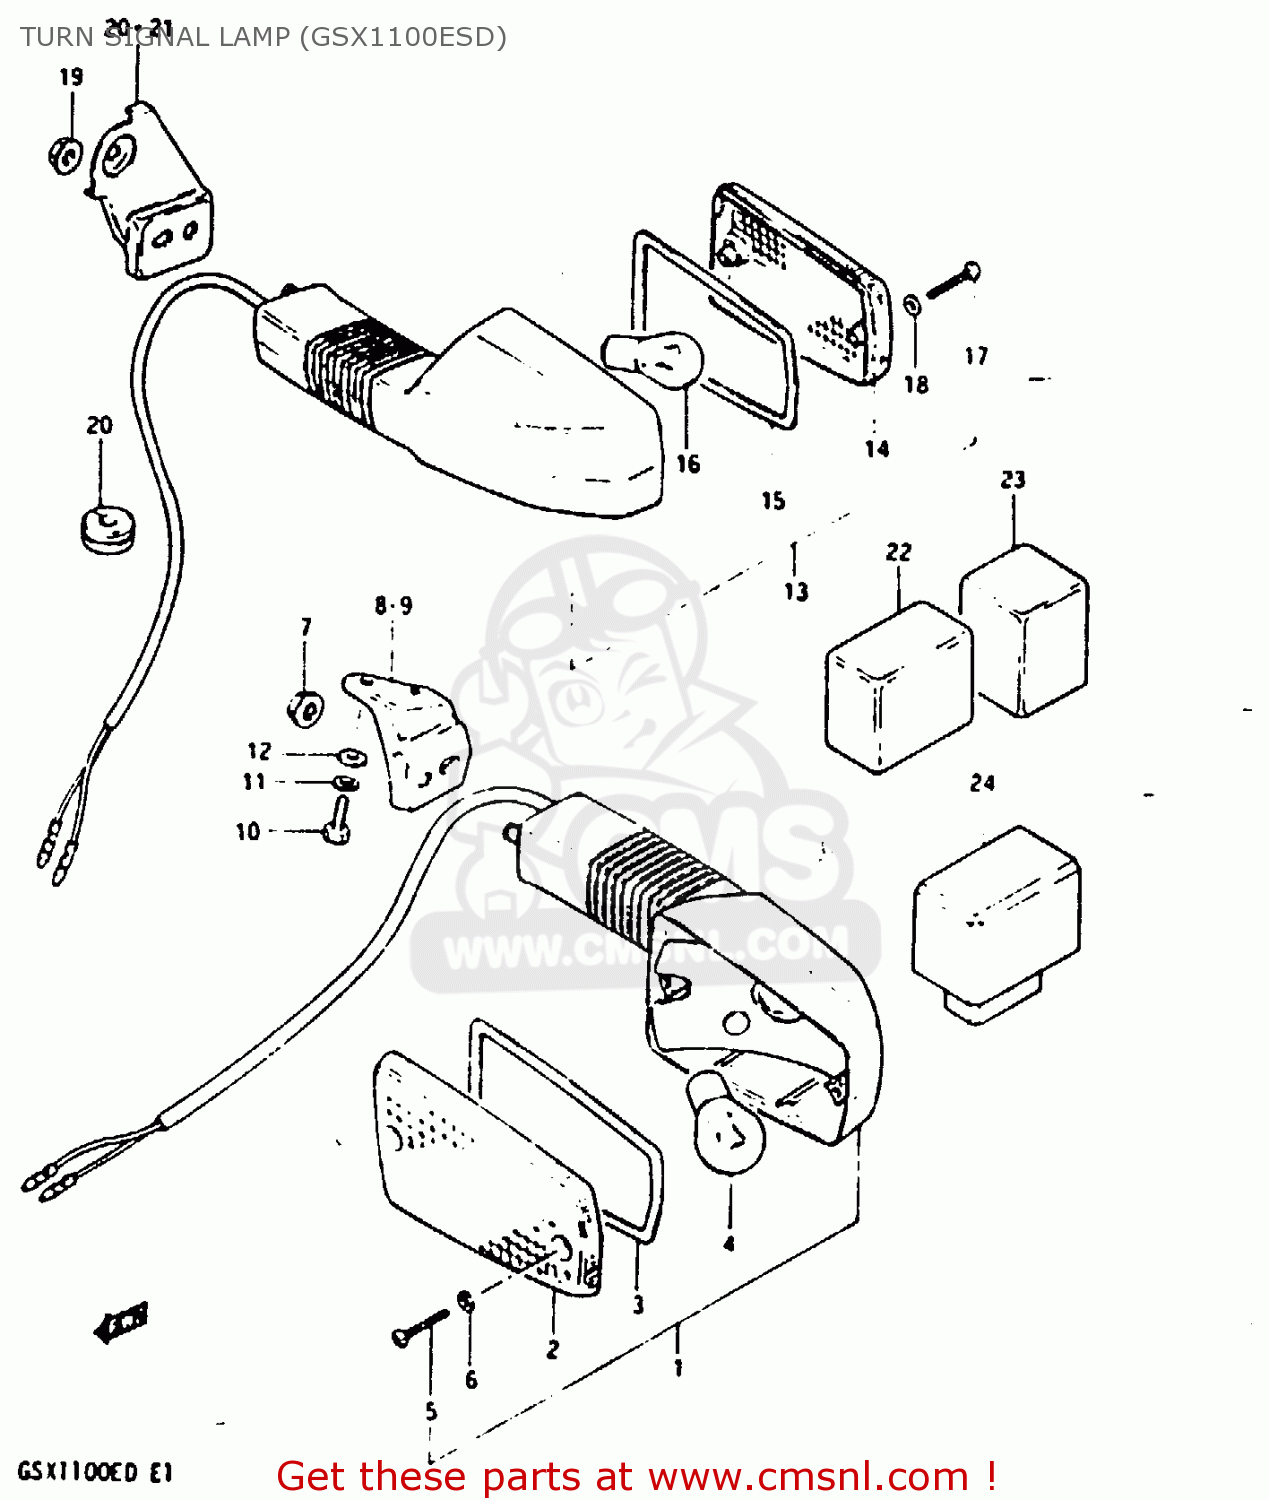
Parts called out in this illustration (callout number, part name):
1	LAMP ASSY, FRONT TURN SIGNAL
2	LENS
3	GASKET (NAS)
4	BULB(12V21W)
5	SCREW
6	GASKET (NAS)
7	NUT
8	BRACKET,FRONT TURN SIGNAL
9	BRACKET,FRONT TURN SIGNAL
10	BOLT
11	LOCK WASHER
12	WASHER
13	LAMP ASSY, REAR TURN SIGNAL
14	LENS,TURN SIGN
15	GASKET (NAS)
16	BULB(12V21W)
17	SCREW
18	GASKET (NAS)
19	NUT
20	BRACKET,REAR TURN SIGNAL
21	BRACKET,REAR TURN SIGNAL
22	RELAY ASSY,TURNSIGNAL
24	UNIT,TURN SIGNAL CONTROL
